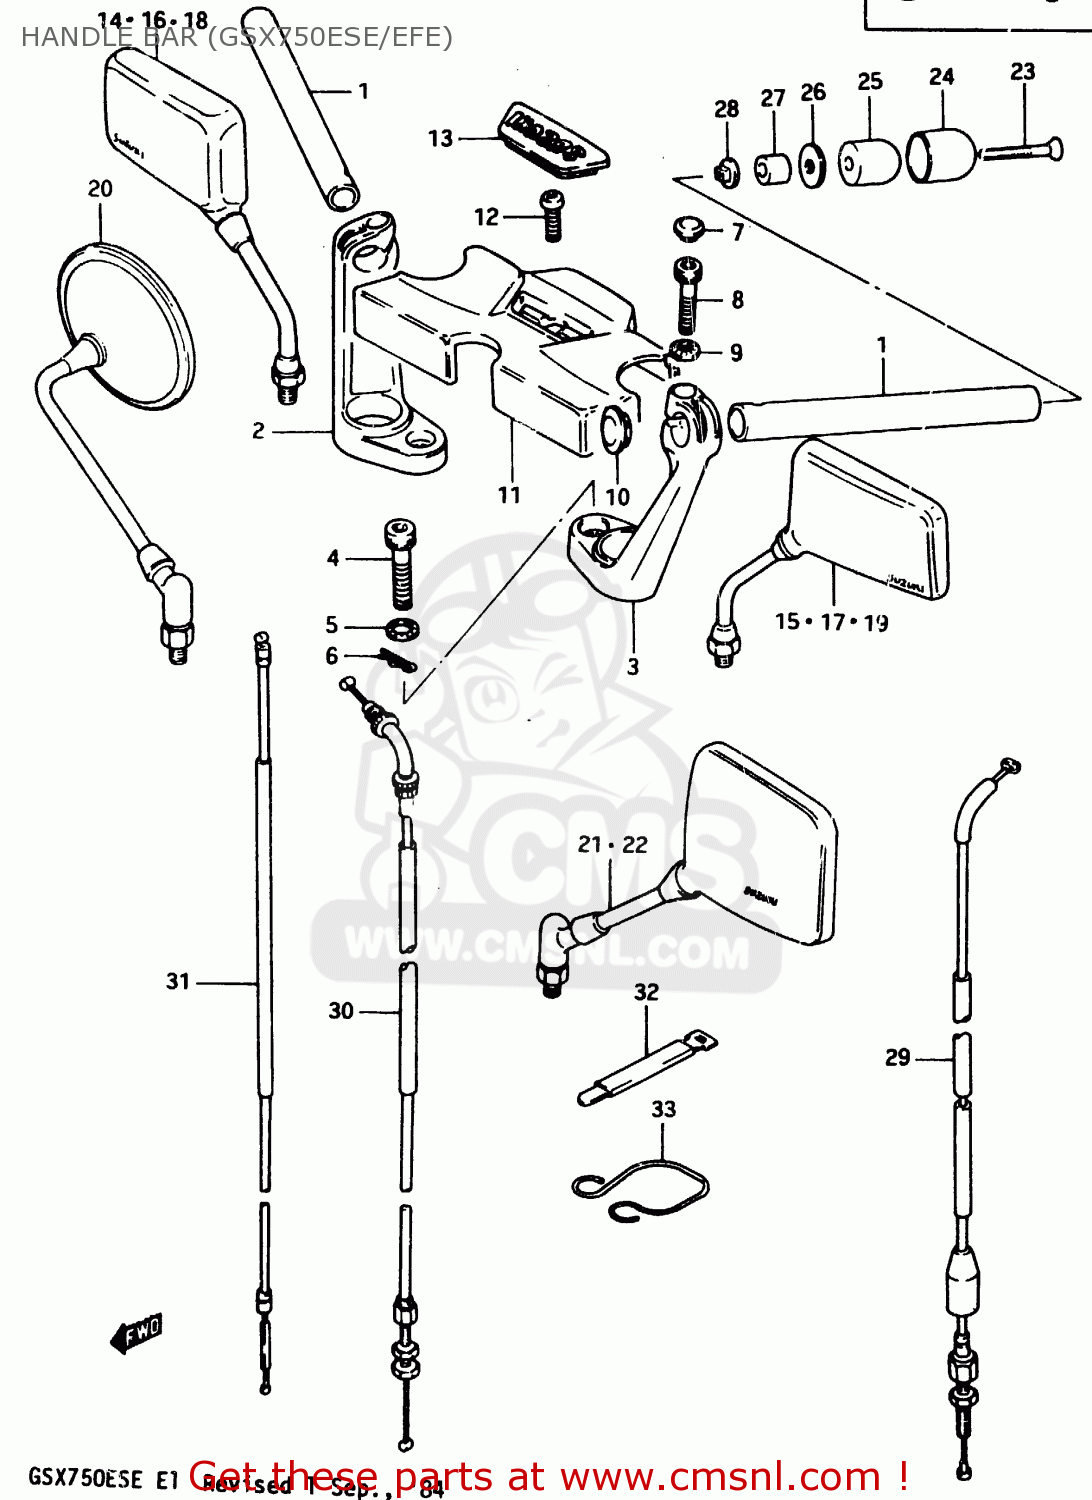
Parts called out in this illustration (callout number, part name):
1	HANDLEBAR
2	HOLDER,HANDLEBAR,RIGHT
3	HOLDER,HANDLEBAR,LEFT
4	BOLT 10X50
5	WASHER
6	CLIP
7	CAP(OD:14.5)
8	BOLT 8X35
9	WASHER
10	CAP,GRIP END
11	PAD,HANDLE
12	SCREW
13	CAP,HANDLE PAD
14	MIRROR ASSEMBLY,RIGHT
15	MIRROR ASSEMBLY,REAR VIEW
16	MIRROR, REAR VIEW RH
17	MIRROR, REAR VIEW LH
18	MIRROR, REAR VIEW RH
19	MIRROR, REAR VIEW LH
20	MIRROR, REAR VIEW
21	MIRROR ASSEMBLY,REAR VIEW
22	MIRROR ASSEMBLY,REAR VIEW
23	SCREW 6X65
24	CAP,BALANCER
25	BALANCER,HANDLE
26	SPACER,BALANCER
27	EXPANDER,BALANCER
28	NUT
29	CABLE ASSY,CLUTCH
30	CABLE ASSY,THROTTLE
31	CABLE COMP,STARTER
32	CLAMP
33	GUIDE,CABLE/HARNESS
